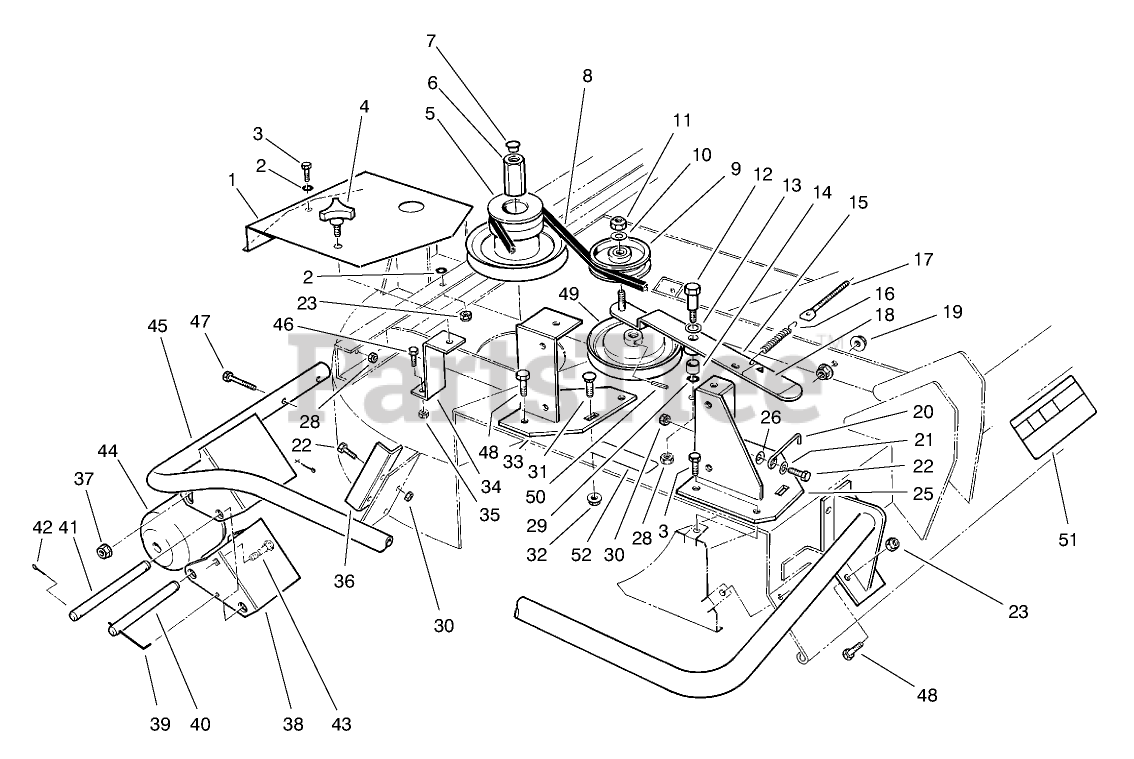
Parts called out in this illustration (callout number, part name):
1	Cover-Deck, R.H.
2	WASHER-PLAIN
3	SCREW-HH
5	Pulley-Splined
6	NUT-PULLEY
7	NUT-COVER
8	V-BELT
9	PULLEY-IDLER
10	WASHER-FLAT
11	NUT-LOCK, NI
12	SCREW-PIVOT
13	WASHER-THRUST
14	BUSHING
15	Arm Assembly (Incl. Ref. #14 & 18)
16	SPRING-TRACTION
17	ROD-THREADED
18	DECAL-WARNING
19	NUT-HF
21	WASHER-FLAT
22	SCREW-HH
23	NUT-LOCK, NI
25	BRACKET WA - RH
26	WASHER-BELLEVILLE
28	NUT-LOCK, NI
29	WASHER-THRUST
30	NUT-LOCK, NI
31	SCREW-CARR
32	NUT-HHF, WHIZ
33	BRACKET-LH
34	Support-Cover
35	NUT-LOCK, NI
36	DEFLECTOR STOP B
37	NUT-FLANGE
38	Bracket-Roller
39	PIN - SPECIAL
40	SHAFT
42	PIN-COTTER
43	SCREW-CARR
44	ROLLER - 4" DIA
45	Bumper
47	SCREW-HH
48	SCREW-HH
49	Pulley-Gear Box
50	PIN-ROLL
51	DECAL-DANGER, THROWN OBJECT
52	DECAL-DANGER
